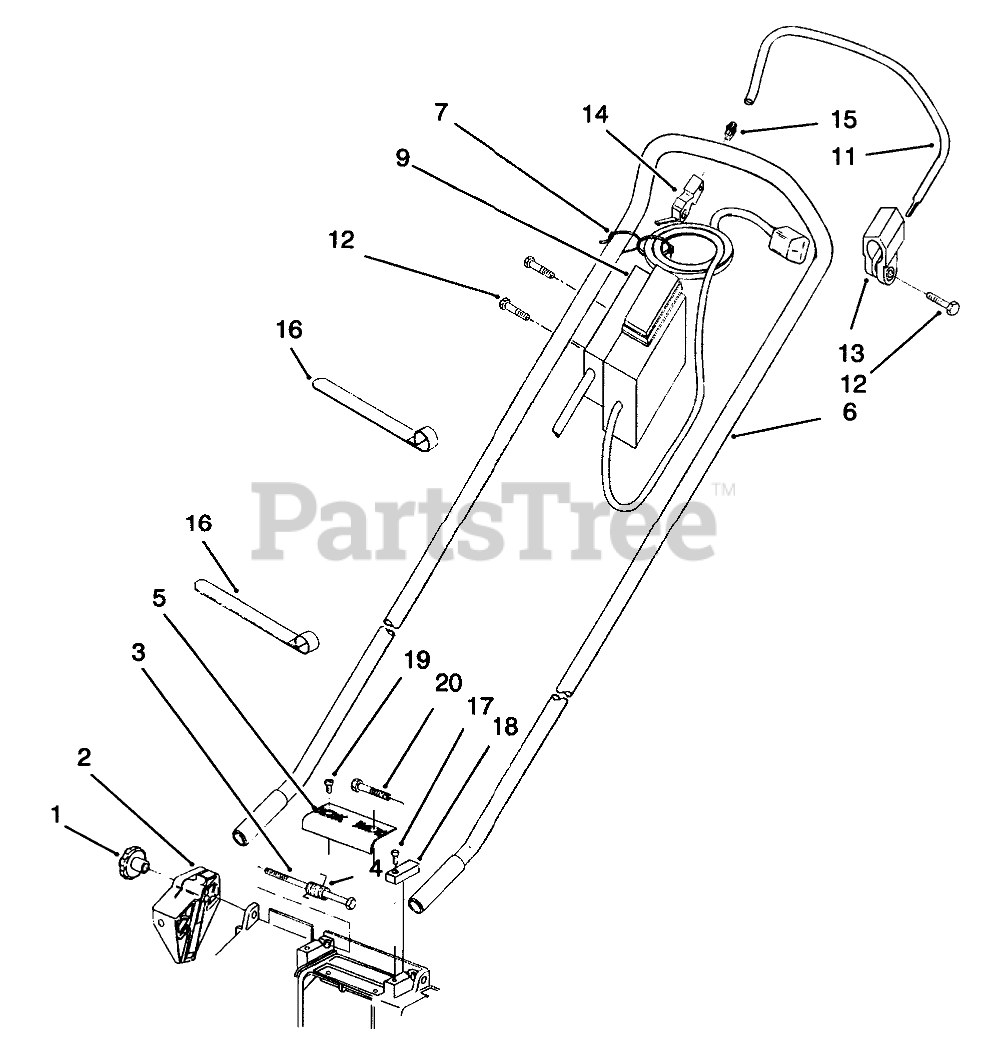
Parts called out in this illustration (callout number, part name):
2	Mount-Handle R.H.
3	BOLT-LONG
4	SPRING-DOOR
5	GRIP-UPPER
6	HANDLE
7	TIE-CABLE
9	SWITCH-PLUG ASSEMBLY, GB
11	LEVER - SWITCH
12	SCREW - TAPPING
13	MOUNT - LEVER
14	BUSHING - LEVER
16	Binder-Cable
17	SCREW-CAP, HINGE
18	CAP-BOLT
19	SCREW-PPH, PLASTITE
20	BOLT-SHORT
